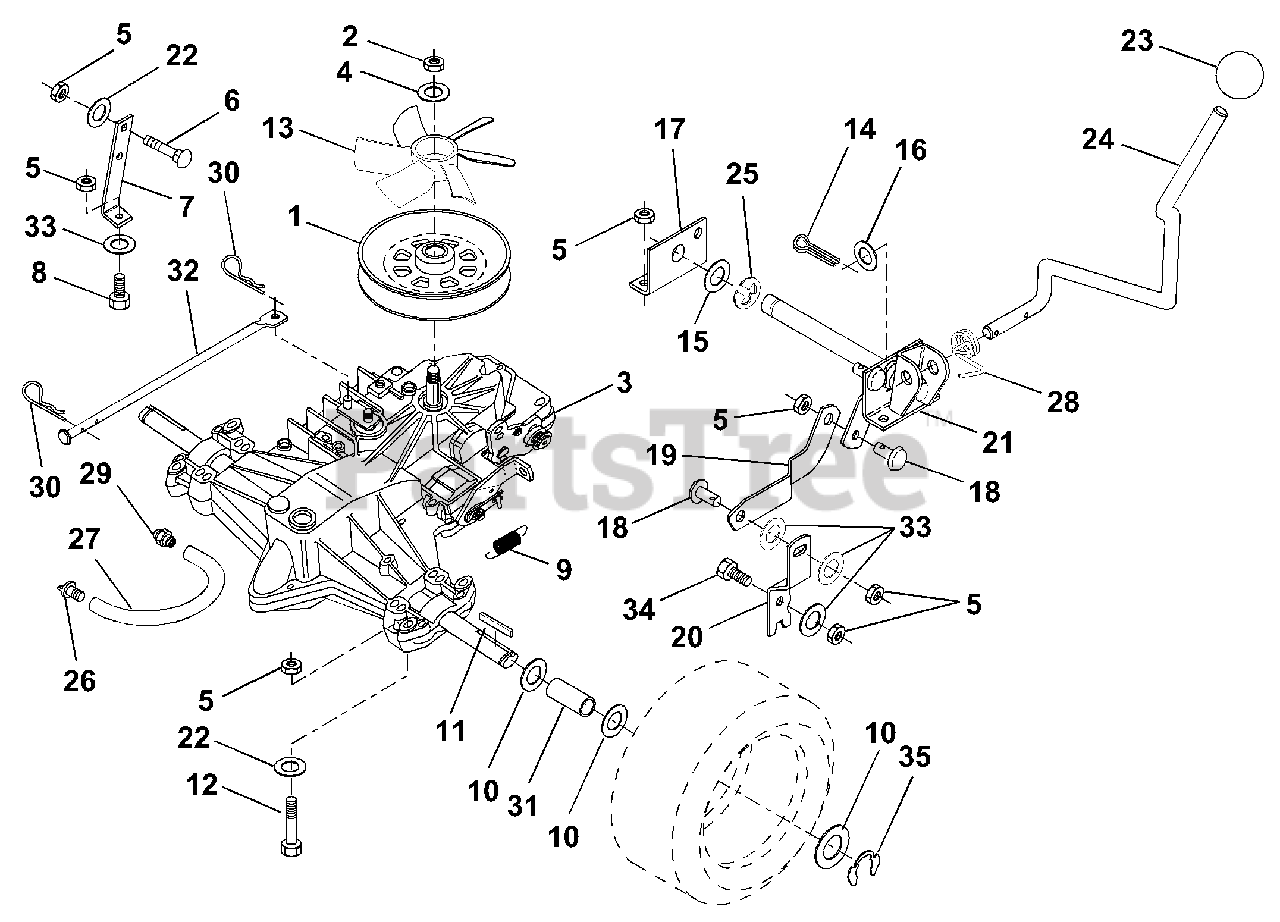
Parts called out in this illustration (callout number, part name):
2	Nut Lock 1/2-20 UNF x 3/4 x 7/16
3	Transaxle, Hydro 0310-0500
4	Washer 17/32 x 1-3/16 x 12 Ga.
5	Nut Lock Hex w/Ins. 5/16-18
6	Bolt, Carriage
7	Strap, Torque
8	Bolt Fin Hex 5/16-18 x 1-1/2
9	Spring Brake
10	Washer 25/32 x 1-1/4 x 16 Gauge
11	Key, Square
12	Bolt, Hex Head 5/16-18 x 2-1/2
13	Fan, Transaxle, Hydro
14	Pin, Cotter 1/8 x 1
15	Washer 21/32 x 1-1/4 x 13 Ga.
16	Washer 17/32 x 3/4 x 16 Ga.
17	Support, Shift Handle
19	Link, Shift
20	Lever, Shift
21	Pivot Shaft Assembly
22	Washer 11/32 x 11/16 x 16 Ga.
23	Knob, Shifter
24	Rod, Shifter
26	Cap, Vent Hose
27	Hose, Vent
28	Spring, Torsion
29	Nipple, Vent Hose
30	Retainer Spring
32	Actuator, Bypass, Hydro
33	Washer 11/32 x 3/4 16 Ga.
34	Bolt Hex Hd. 5/16-18 x 1
